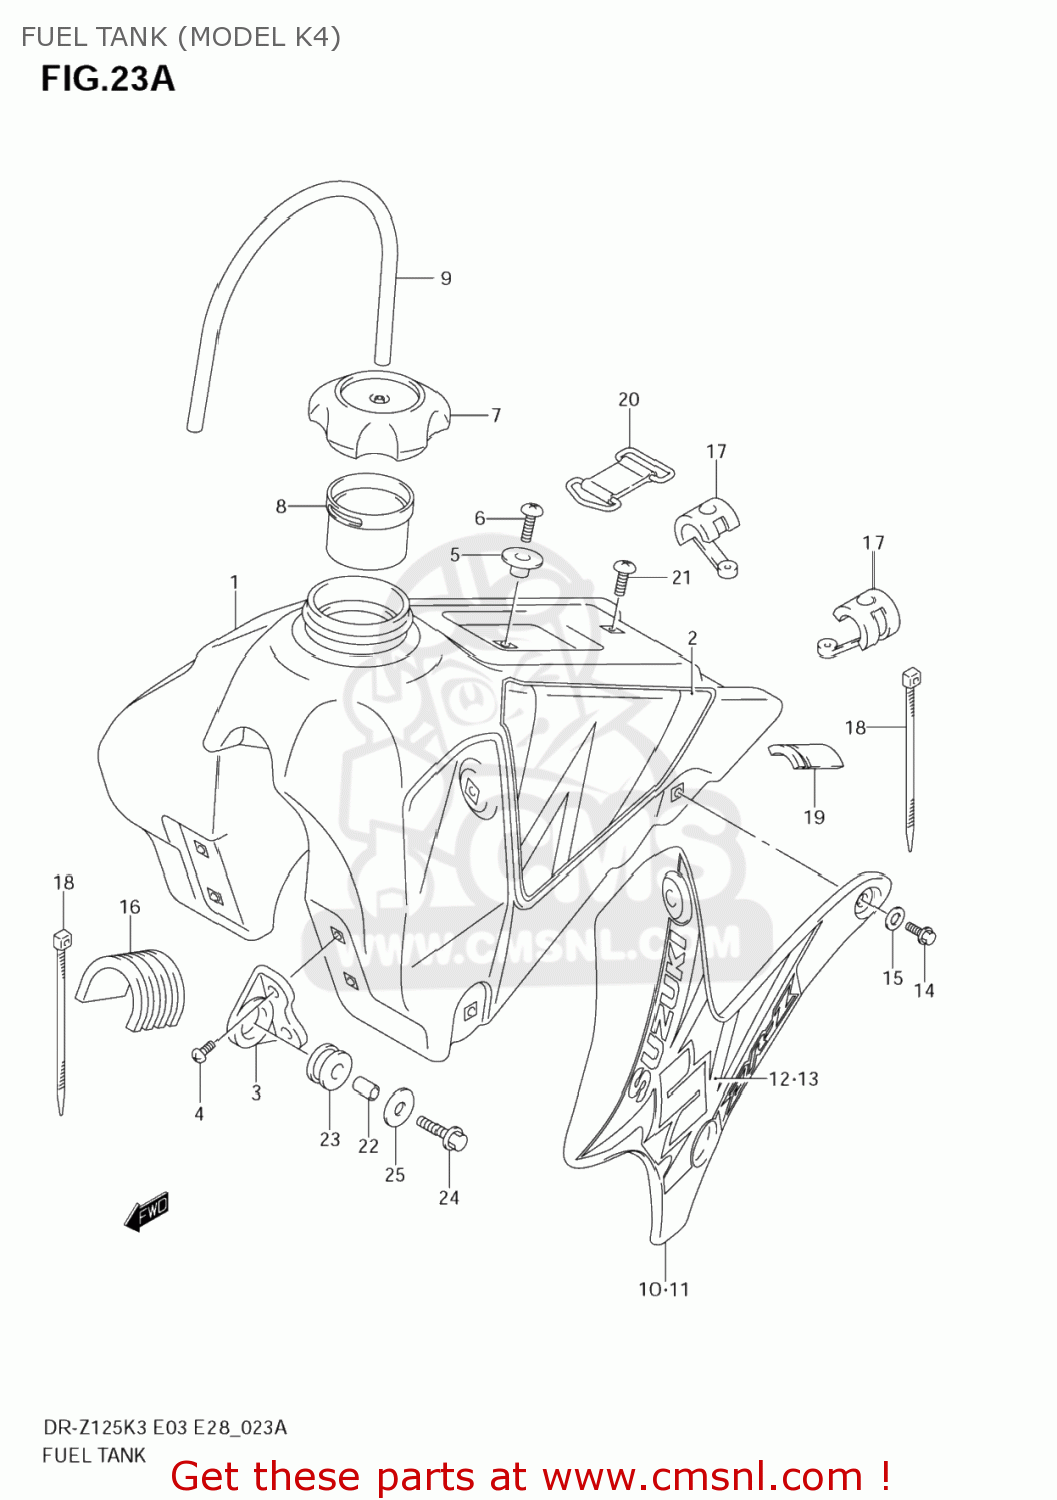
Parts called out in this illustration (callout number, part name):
1	TANK ASSY,FUEL(YELLOW)
2	TAPE SET,FUEL TANK
3	BRACKET,FUEL TANK FR
4	BOLT
5	HOOK,SEAT FR
6	SCREW
7	CAP ASSY,FUEL TANK FILLER
8	TUBE,FILLER INLET
9	HOSE(5X8.2X600)
10	COVER, TANK FRONT RH (YELLOW)
11	COVER, TANK FRONT LH (YELLOW)
12	TAPE,FUEL TANK COVER,R
13	TAPE, FRONT COVER LH
14	BOLT
15	WASHER
16	CUSHION,FUEL TANK
17	CUSHION,FUEL TANK SIDE
18	CLAMP(L:300)
19	CUSHION,FUEL TANK RR
20	BAND,FUEL TANK RR
21	SCREW
22	SPACER(6.5X9X13.5)
23	CUSHION,FUEL TANK FR
24	SCREW
25	WASHER(6.5X24X1.2)
